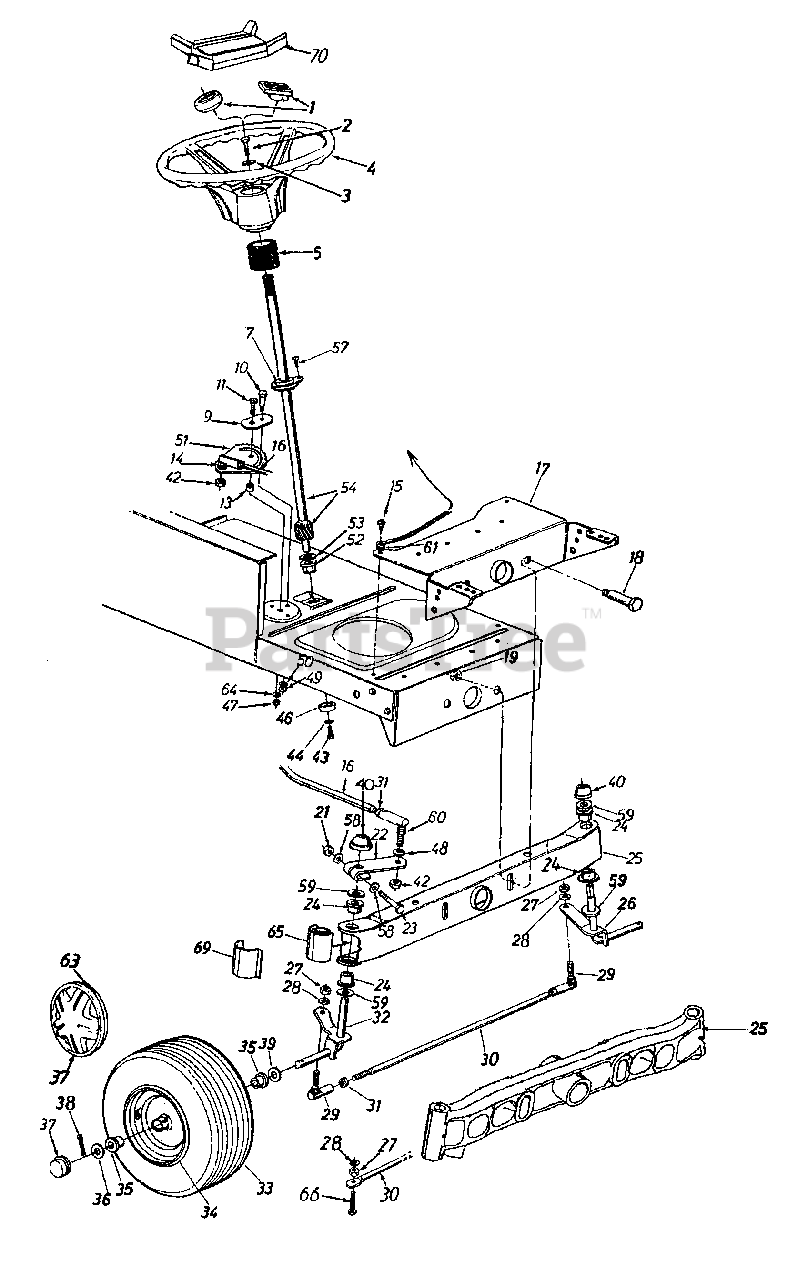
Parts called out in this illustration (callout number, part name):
1	Steering Wheel Cap
1	Steering Wheel Cap (Sq.-MTD)
1	Steering Wheel Cap (Sq.-No logo)
2	Hex Bolt 5/16-18 x 1" Lg.
3	Belleville Wash. .345" I.D.
4	Steering Wheel (3 Spoke)
4	Steering Wheel (4 Spoke)
5	Steering Bellow-9" (Style 0)
5	Steering Bellow-3.25" (Style 7)
6	Hex Jam Nut 7/16-20 Thd.
7	Flange Bearing.628" I.D. x 1.36 O.D.
8	Ball Joint 7/16-20 Thd.
9	Retainer Plate
10	Shoulder Bolt .437 x .35 Lg. 5/16-18
11	Hex Bolt 3/8-24 x 1.0" Lg. (Gr. 5)
13	Spacer.380" I.D. x .625" O.D.x
14	L-Wash. 3/8" I.D. (H.D.)
15	Hex Wash. Hd. Self-Tap Scr.
16	Steering Drag Link
18	Shoulder Bolt
19	Flanged L- Nut 3/8-16 Thd.
21	Hex L-Nut 5/16-24 Thd.
22	Steering Arm Front Axle
23	Hex Bolt 5/16-24 x 2.25" Lg.
24	Hex Flg. Brg. .632 I.D.
25	Pivot Bar Ass'y. (Cast Iron)
25	Grease Fitting (Cast Iron) Grease Plug 15" x 6"
26	Front Axle Ass'y.-L.H. 15" x 6"
27	Hex Nut 3/8-24 Thd.
28	L-Wash. 3/8" I.D.
29	Ball Joint 3/8-24 Thd.
30	Tie Rod
31	Hex Jam Nut 3/8-24 Thd.
32	Front Axle Ass'y.-R.H. 15" x 6"
36	Fl-Wash 635 I.D. x 1.59" O.D.
37	Front Wheel Hub Cap
37	Spoked Hub Cap (Yellow-Opt.)
37	Spoked Hub Cap (Gray-Opt.)
37	Spoked Hub Cap (Beige-Opt.)
38	Cotter Pin 1/8" Dia. x 1.25"
39	Fl-Wash 640" I.D. x 1.24" O.D.
40	Push Cap 5/8" Dia. Rod
42	Hex Jam Nut 3/8-24 Thd.
43	Hex Patch Bolt 5/16-18 x .62"
47	Hex Cent. L-Nut 3/8-24 Thd.
48	L-Wash. 3/8" I.D.
49	Hex Cent. L-Nut 5/16-18 Thd.
50	L-Wash. 5/16" I.D.
51	Steering Gear Segment
52	Hex Flg. Brg. .634 I.D.
53	Fl-Wash. (Hardened)
54	Steering Shaft
57	Oval Hd. Cr.-Sunk Scr. (Style A)
58	Wave-Wash. .32" I.D. x .60" O.D.
59	Fl-Wash. (Hardened)
60	Drag Link Ball Joint 7/16-20 Thd.
63	Spring Clip
64	Bell-Wash. .39" I.D. x 1.38" O.D.
65	Pivot Bar End Cap
66	Hex Bolt 3/8-24 x 1.5" Lg. (Gr. 5)
69	Axle Cap
70	Steering Wheel Insert
